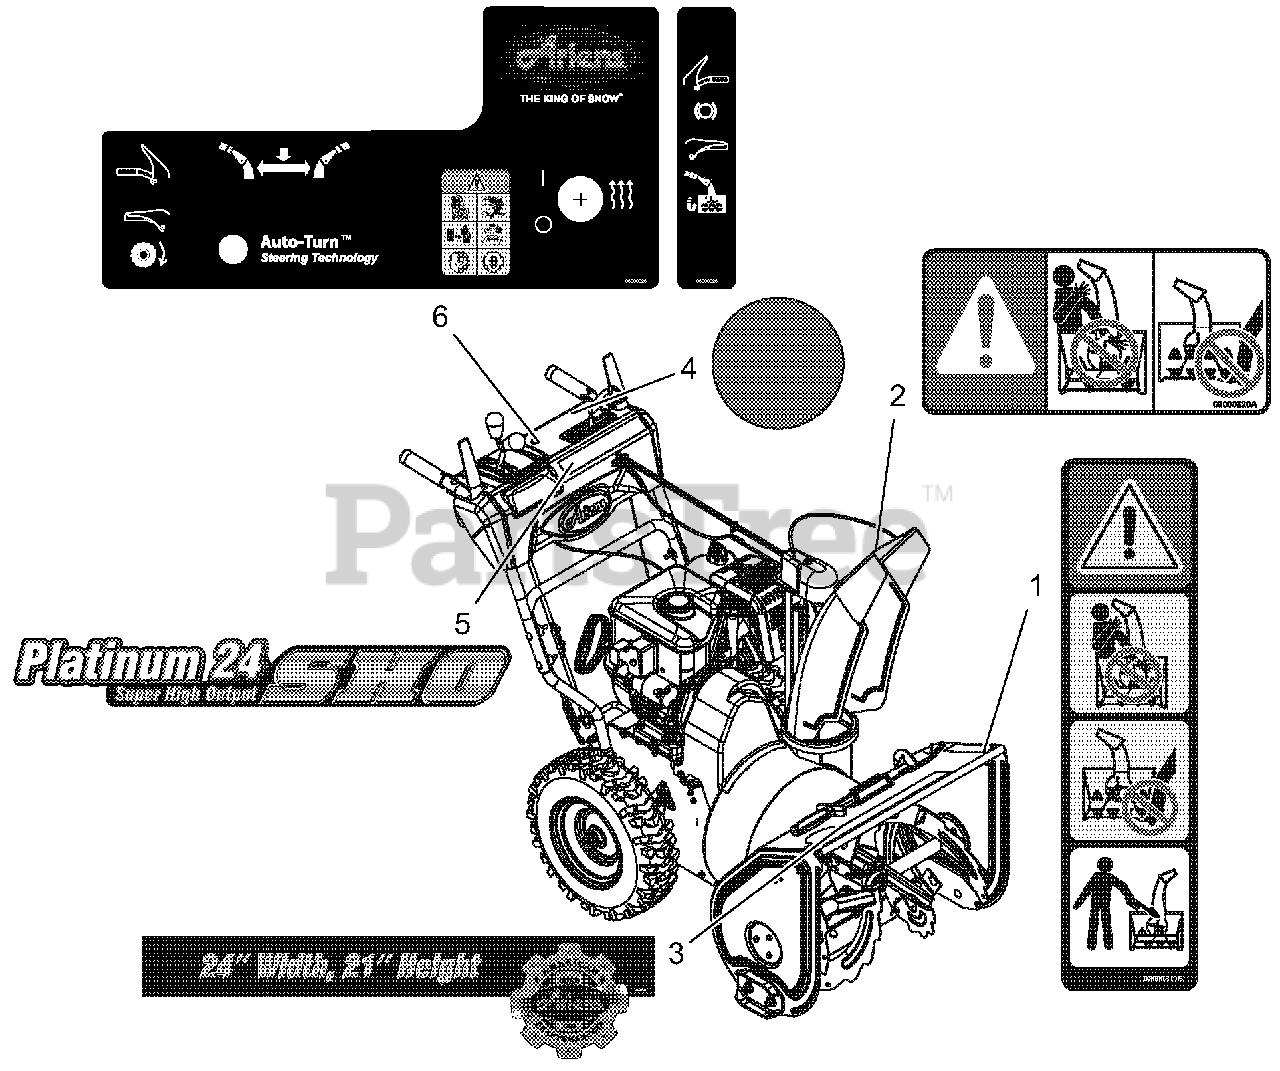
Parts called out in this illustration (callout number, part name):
1	DECAL, DANGER - ROTATING PARTS
2	DECAL, DANGER
4	DECAL,AUTODIFFERENTIAL
5	DECAL,DASH-PLATINUM 24 SHO
6	DECAL,CONTROL-LRG,QT2
